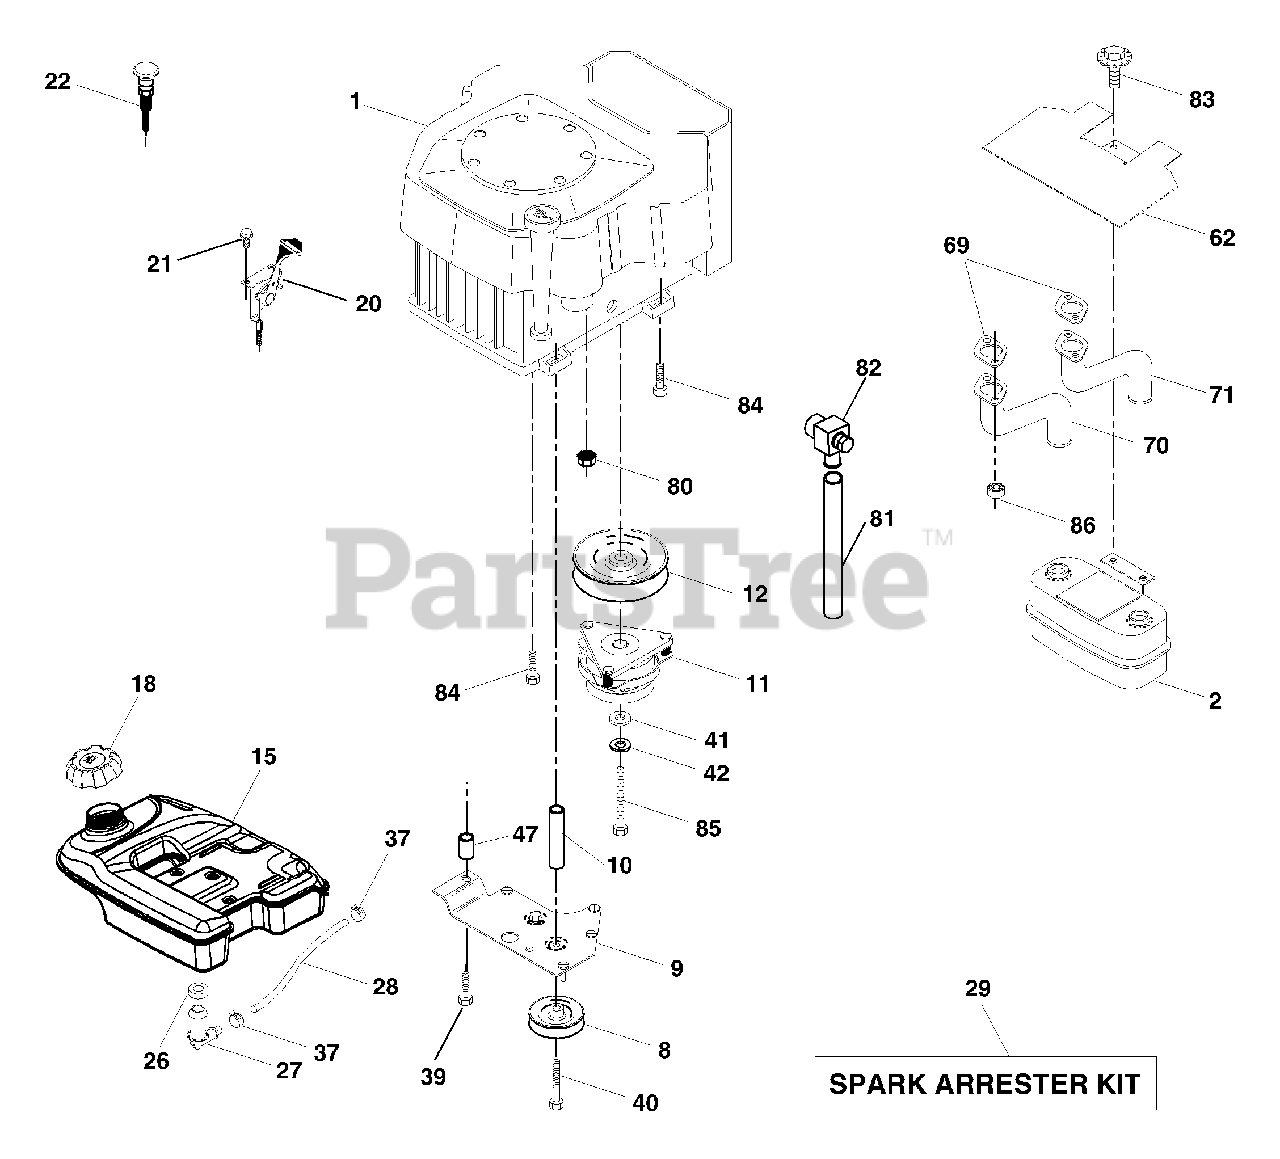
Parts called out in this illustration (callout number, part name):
2	Muffler Side
8	Pulley V-Idler
9	Keeper Asm. Belt Engine VGT
11	Clutch Electric
12	Pulley Engine VGT Elect Clutch
15	Tank Fuel Rear 5.0
18	Cap Fuel
20	Control Throttle
21	Screw Hwhd Hi-Lo #13-16 x 3/4
22	Control Choke
25	Nut Keps 3/8-24
26	Bushing
27	Stem Tank Fuel
28	Fuel Line
29	Spark Arrester Kit
31	Clip Push-In Hinged
37	Clamp Hose
39	Screw TT 3/8-16 x 2-1/4 unc
40	Screw TT 3/8-16 x 4 unc
41	Washer 1-1/2 OD X 15/32 ID X .250
42	Washer Lock 7/16
43	Bolt Hex 7/16-20 X 3.75 Ga. 5
62	Shield Heat Muffler
70	Tube Exhaust LH
71	Tube Exhaust RH
74	Elbow Street Brass
80	Nut Flange M8-1.25
81	Oil Drain Tube
82	Valve Drain Oil
83	Bolt 5/16-18 unc x 1-3/4 W/Sems
84	Screw 3/8-16 x 1-1/2
86	Nut Hex Flange Toplock M8-1.25
